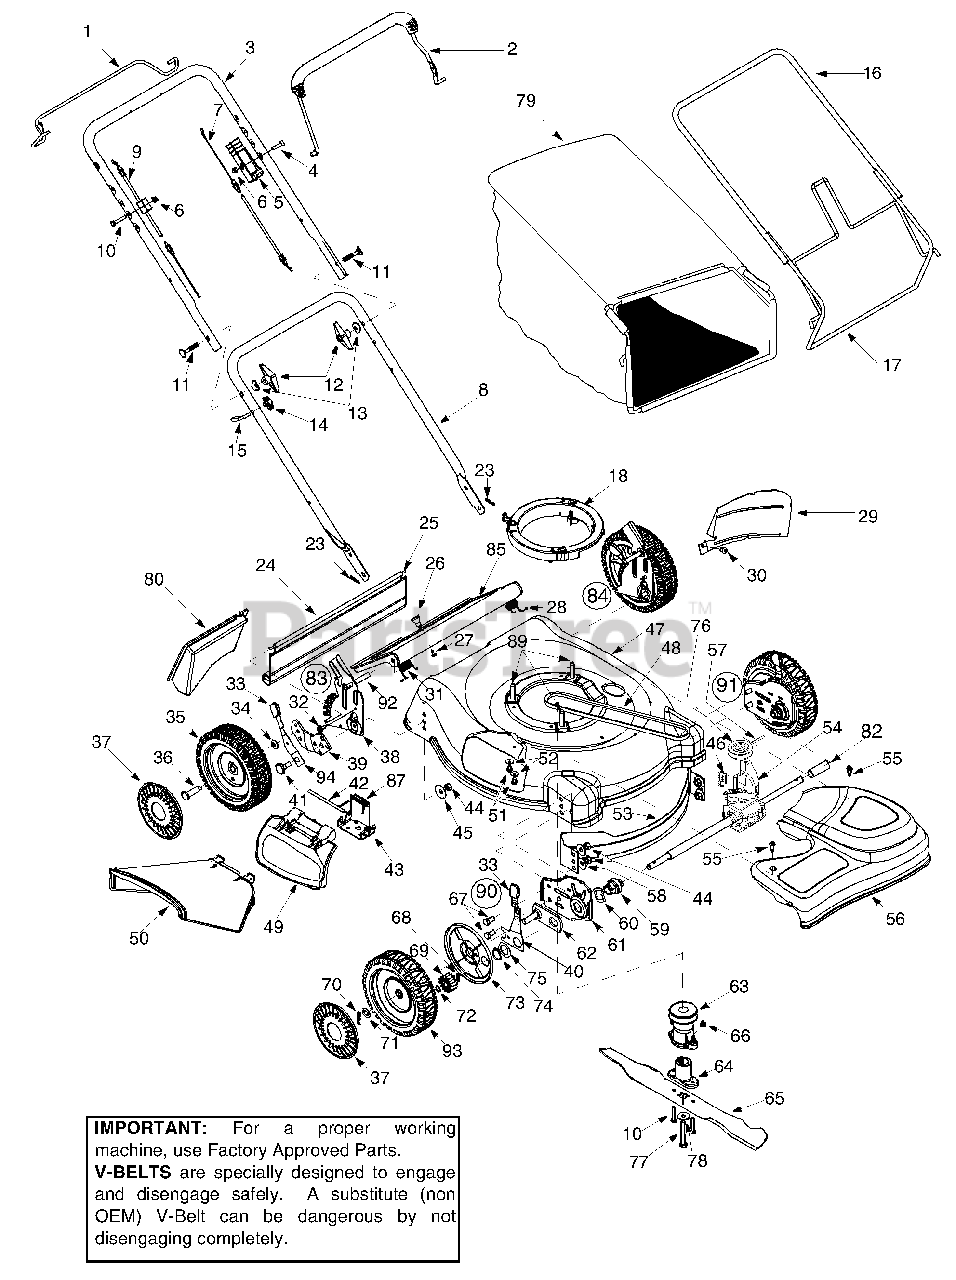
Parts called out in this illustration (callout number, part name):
2	Blade Control Handle
5	Control Housing
6	Hex Lock Nut 1/4-20
7	Control Cable: 43"
9	Drive Cable
10	Hex Screw 1/4-20 x 1.5"
11	Carriage Bolt
12	Handle Knob
13	Saddle Washer
15	Rope Guide
23	Hairpin Clip
24	Rear Trail Shield
25	Wire: Trail Shield
27	Scr. Tr. Mach. #10-24 x 0.380"
28	Torsion Spring LH
30	Scr. AB 1/4-14 x 0.625"
31	Torsion Spring RH
32	Hex Scr. w/ Wash. 1/4-14 x 0.62"
33	Knob
34	Bell Washer .375 x .870
35	Wheel: Rear
36	Shoulder Screw
37	Hubcap
38	Handle Bracket Assembly LH
38	Handle Bracket Assembly RH
39	Pivot Bar LH
39	Pivot Bar RH
40	Front Lever RH
40	Front Lever LH
41	Shoulder Screw
42	Hinge Pin
45	Flat Washer
46	Belt Tension Spring
49	Mulch Plug
50	Discharge Deflector SD
51	TT Screw 1/4-20 x 0.5"
52	Bell Washer 0.265" x 0.75"
55	Screw #12 x 0.457"
56	Front Drive Cover
58	Bell Washer
59	Bearing Support
60	Wave Washer
62	Pivot Plate Assembly
63	Drive Pulley
64	Blade Adapter
65	Mulching Blade w/ Star: 21"
66	Hex Lock Nut
67	Hex Screw
68	Dowel Pin
69	Gear 14T RH
69	Gear 14T LH
70	Hairpin Clip
71	Flat Washer
72	Snap Ring
73	Wheel Dust Cap
74	Snap Ring
75	Washer DD 1.5" O.D.
76	Input Pulley
78	Bell Washer
79	Grass Bag
80	PLUG-MULCHING BAFFLE
82	Slev. Spacer LH
82	Slev. Spacer RH
83	Height Adj. Assembly RH Complete
84	Height Adj. Assembly LH Complete
90	Height Adj. Assembly RH Complete
91	Height Adj. Assembly LH Complete
93	Wheel:Front
94	Spring Lever
